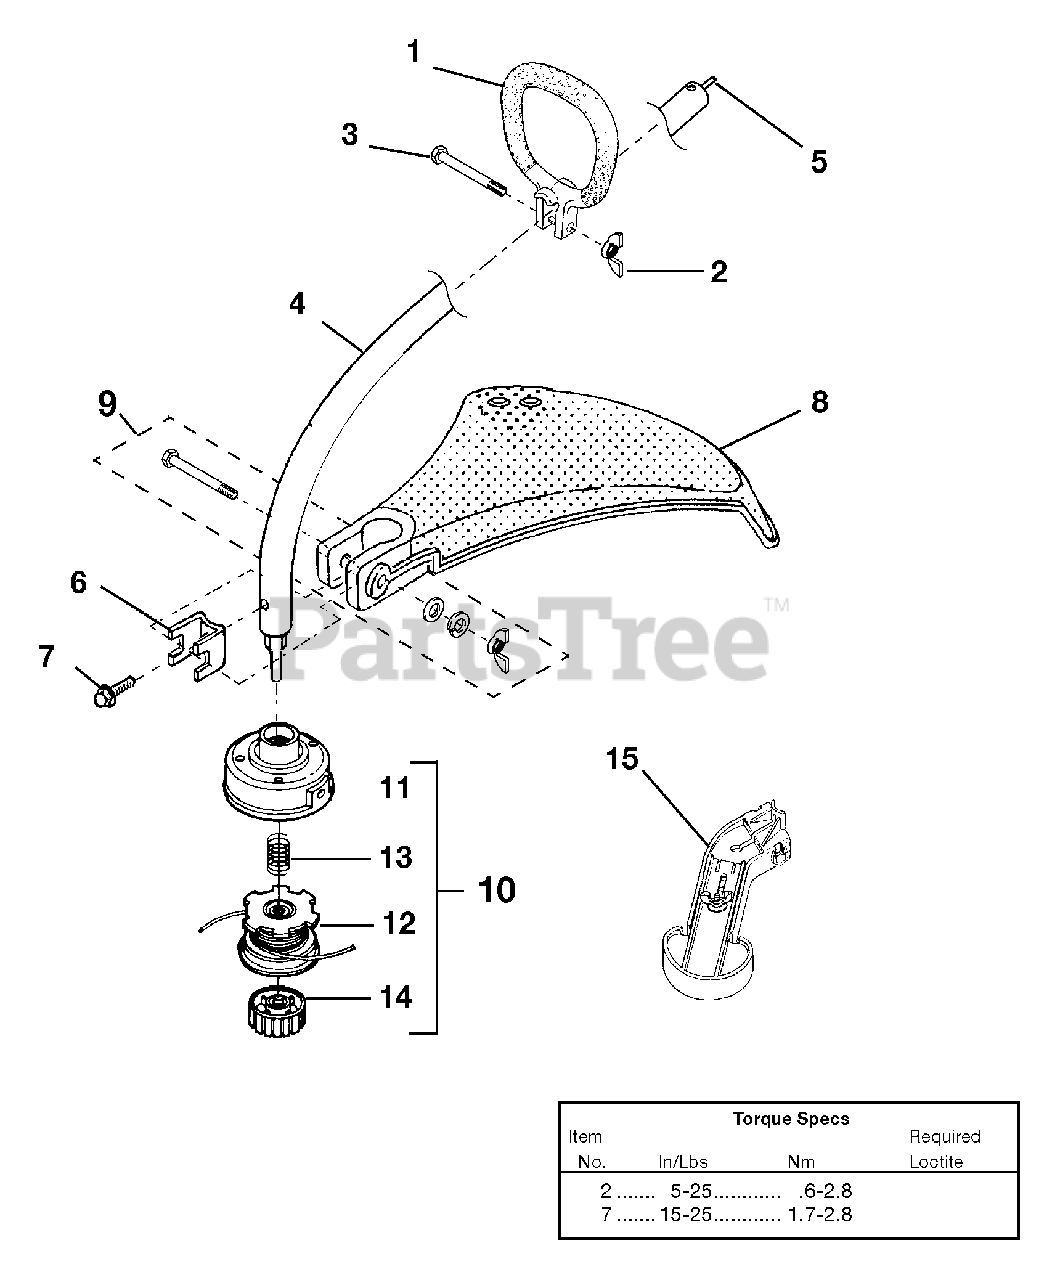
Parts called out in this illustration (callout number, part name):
1	HANDLE ASSY.-Front
2	NUT-Wing, Washer Faced (1/4-20)
3	SCREW-Cap Hex Hd.
4	DRIVESHAFT HOUSING ASSY.
5	SHAFT-Flexible
6	CLAMP
7	SCREW-Sems Hex Hd. (#10-24 X 3/8")
8	DEFLECTOR-GRASS (55 Deg.)
9	FASTENER KIT
10	STRINGHEAD-Complete
11	HOUSING & EYELET (Dual Line)
12	SPOOL & STRING (.080" Line)
13	SPRING-Compression
14	RETAINER-Spool (RH Thread, Black)
15	EDGER GUIDE KIT (UT20933 only)
